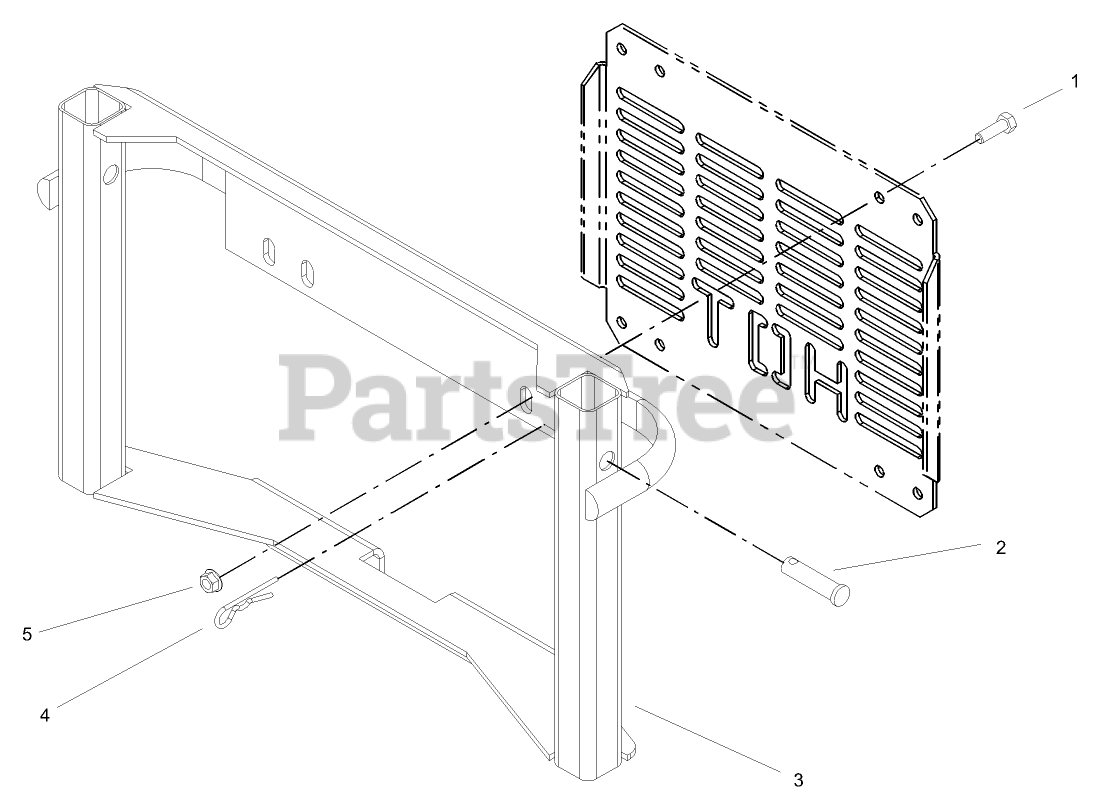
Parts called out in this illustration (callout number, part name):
1	SCREW-HH
2	PIN-CLEVIS
3	BAGGER MOUNT ASM
4	PIN-COTTER
5	NUT-HF
